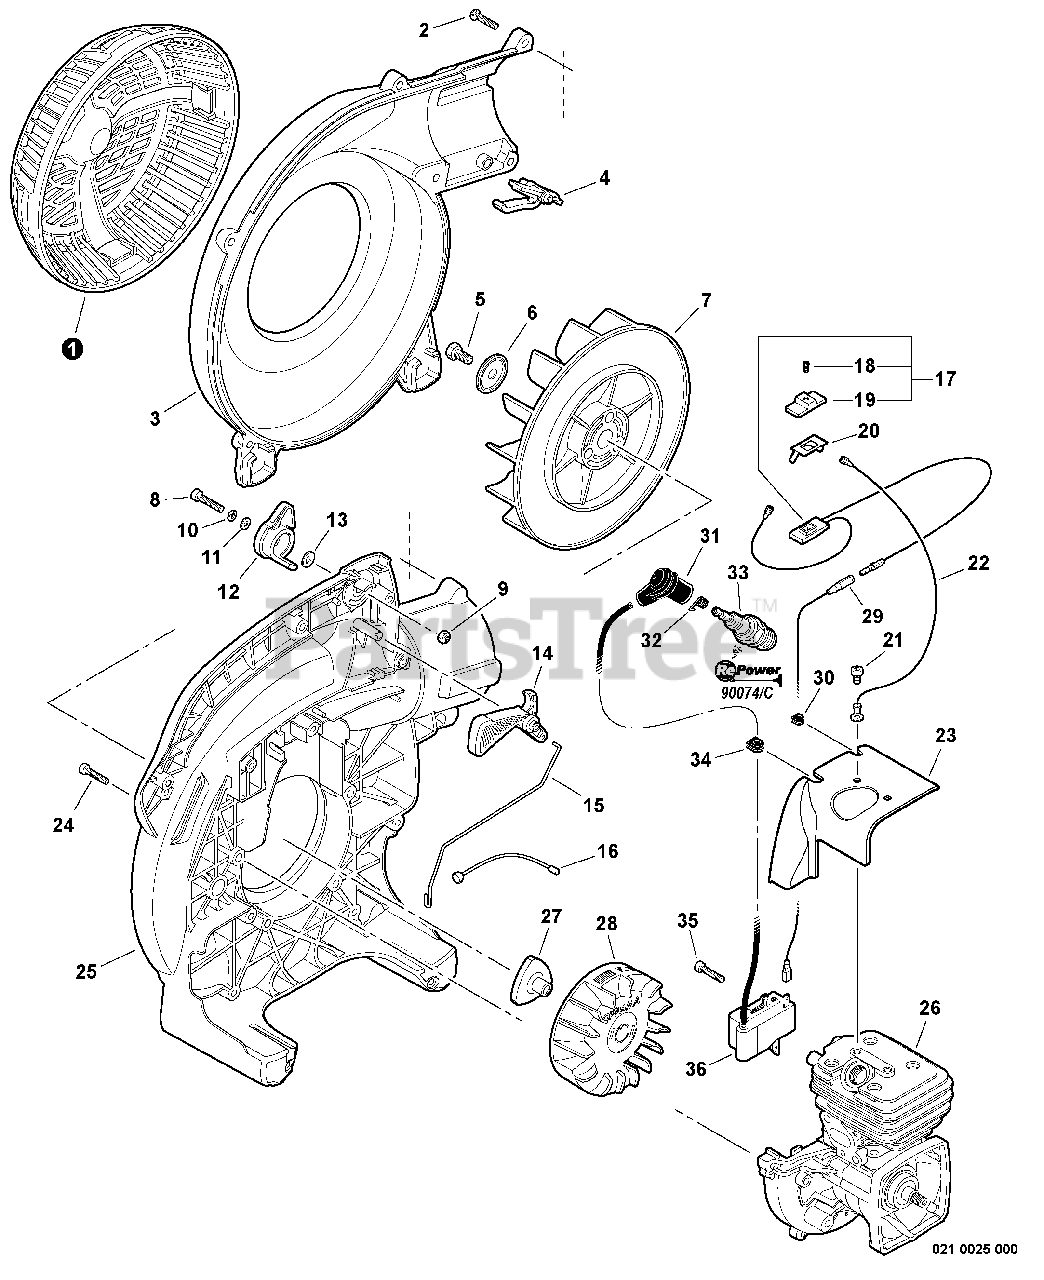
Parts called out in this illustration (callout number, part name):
1	GUARD, DEBRIS
2	SCREW - 5X20
3	COVER, FAN - LEFT
4	LOCK, TUBE
5	BOLT - 8X14
6	WASHER - CUP
8	SCREW - 5X25
9	LOCKNUT - 5
10	LOCKWASHER - 5
11	WASHER - 5
12	LEVER, THROTTLE
13	WASHER - 5
14	TRIGGER, THROTTLE
15	ROD, THROTTLE
16	CABLE, THROTTLE
17	SWITCH, IGNITION
18	SCREW - 3X10
19	KNOB, SWITCH - ORANGE
20	TERMINAL - GROUND
21	SCREW - 5X8
22	LEAD - GROUND
23	SHIELD, CYLINDER
24	SCREW - 4X20
25	COVER, FAN - RIGHT
26	SHORT BLOCK -- SB1104
27	HUB, FAN
28	FLYWHEEL
29	LEAD - IGNITION
31	CAP, SPARK PLUG
32	TERMINAL, SPARK PLUG CAP
33	SPARK PLUG -- BPM-8Y
33	SPARK PLUG -- BPMR-8Y
35	SCREW - 4X20
36	COIL, IGNITION
37	RePower TUNE-UP KIT
